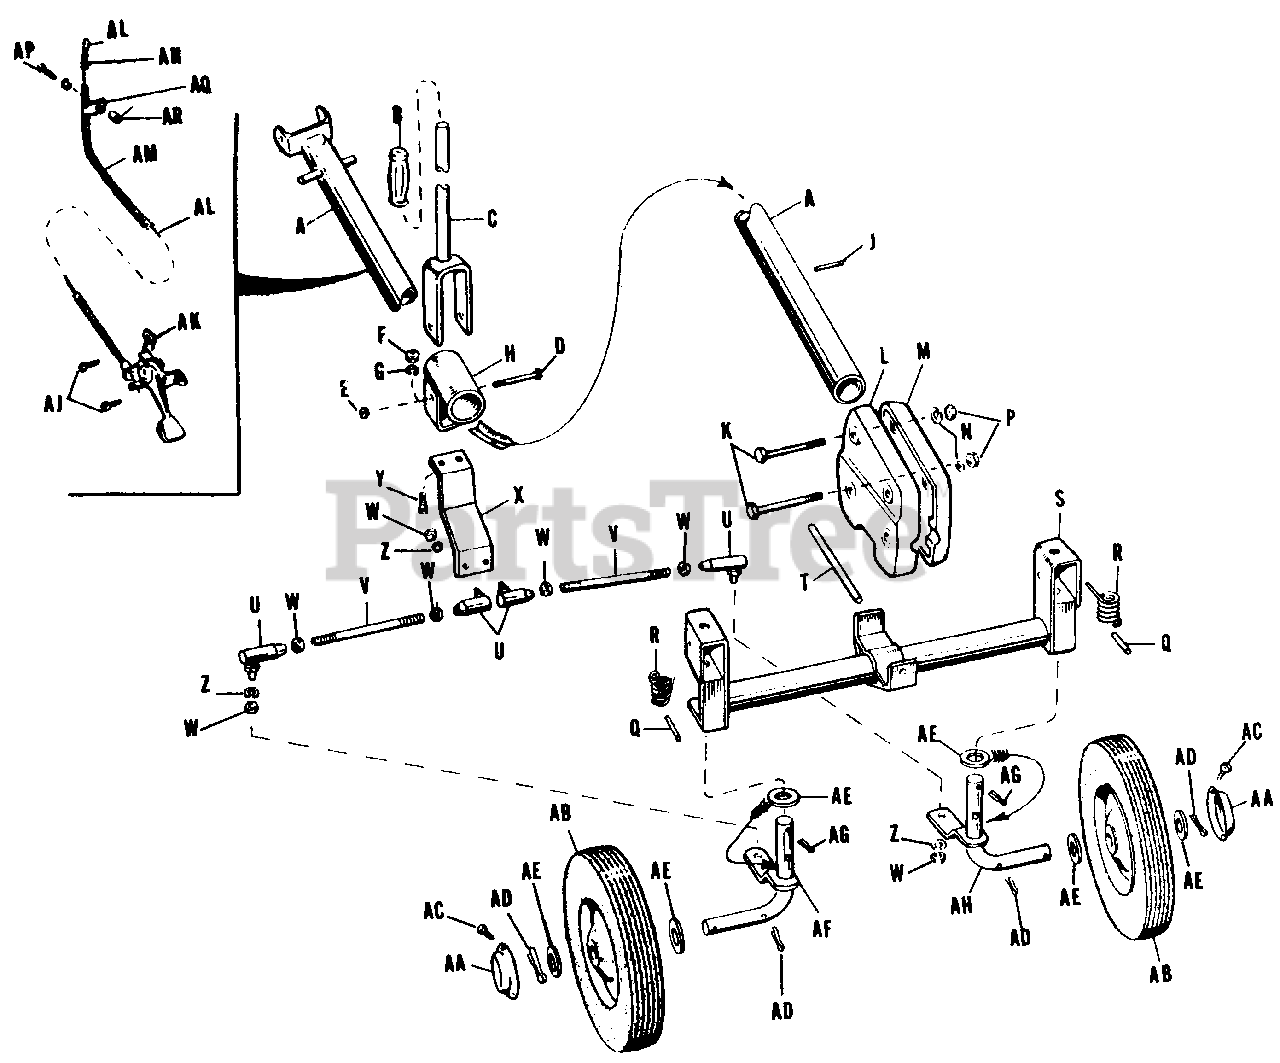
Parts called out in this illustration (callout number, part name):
A	Frame Assembly, Front
B	Grip, Handle
C	Handle Assembly
D	Screw, Hex Hd. Cap, 3/8-16 x 3 1/4"
E	Lock Nut, Hex, 3/8-16
F	Nut, Full Hex, 3/8-16
G	Lock Washer, 3/8"
H	Pivot Assembly, Steering
J	Pin, Roll 7/32 x 1" Long
K	Screw, Hex Cap, 3/8-16 x 3 1/4"
L	Support, Front, R.H.
M	Support, Front, L.H.
N	Lock Washer, 3/8"
P	Nut, Full Hex, 3/8-16
Q	Pin, Roll, 5/16 x 1 1/4
R	Spring, Torsion
S	Axle Assembly, Front
T	Pin, Pivot
U	Joint, Ball
W	Nut, Full Hex. 3/8-24
X	Arm, Lever
Y	Screw, Hex Cap, 3/8-16 x 7/8"
Z	Lock Washer, 3/8"
AA	Hub Cap, Front
AB	Wheel, Front, w/Tire
AC	Screw, Self-tapping No. 10 x 1/2"
AD	Pin, Cotter, 5/32 x 1 1/4"
AF	Spindle Assembly, R.H.
AG	Pin, Cotter, 5/32 x 1"
AH	Spindle Assembly, L.H.
AJ	Screw, Rd. Hd., No. 10-24 x 1/2"
AK	Throttle Lever Control
AL	Throttle Wire
AM	Throttle Cable
AN	Spring, Throttle Wire
AP	Screw and Lock Washer Assembly, 10-32 x 7/8" (for 3851 cable clamp)
AQ	Clamp, Cable
